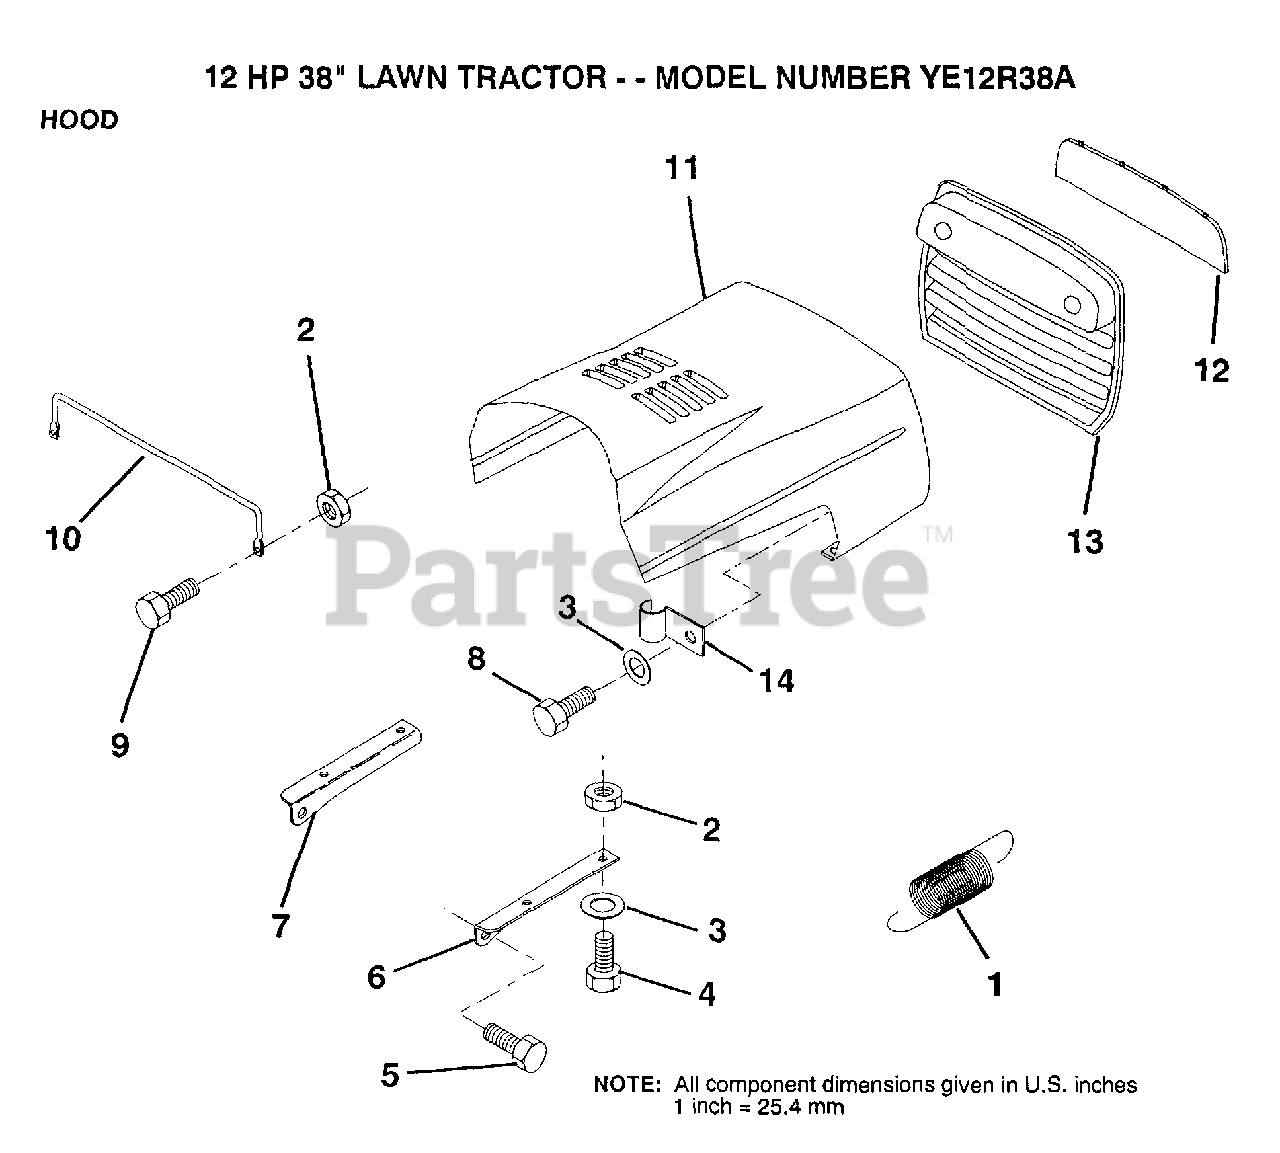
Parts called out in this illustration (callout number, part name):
1	EXT SPRING
2	NUT
3	WASHER
4	BOLT
6	BRKT HOOD RH
7	BRKT HOOD LH
10	"BRACE,HOOD"
11	HOOD
12	LENS
13	GRILL
14	CLIP T
